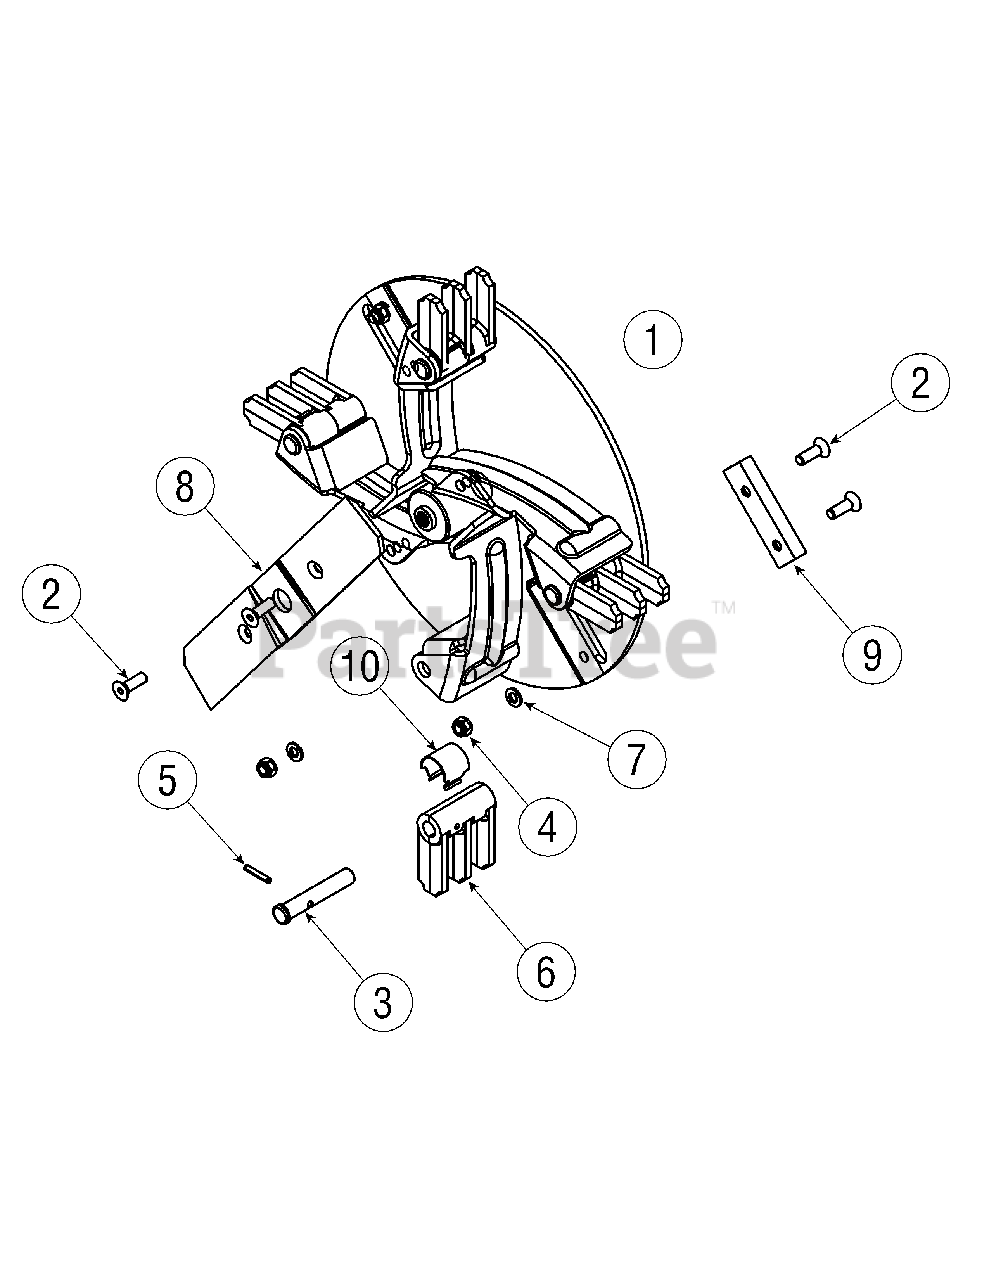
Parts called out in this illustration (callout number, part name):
1	Impeller Assembly Complete
2	Machine Screw, 5/16-24 x 1.0
3	Clevis Pin,.496
4	Hex Lock Nut, 5/16-24
5	Spiral Pin,.156 x 1.0
7	Lock Washer, 5/16
8	Shredder Blade
9	Chipper Blade
10	Retainer Clip
